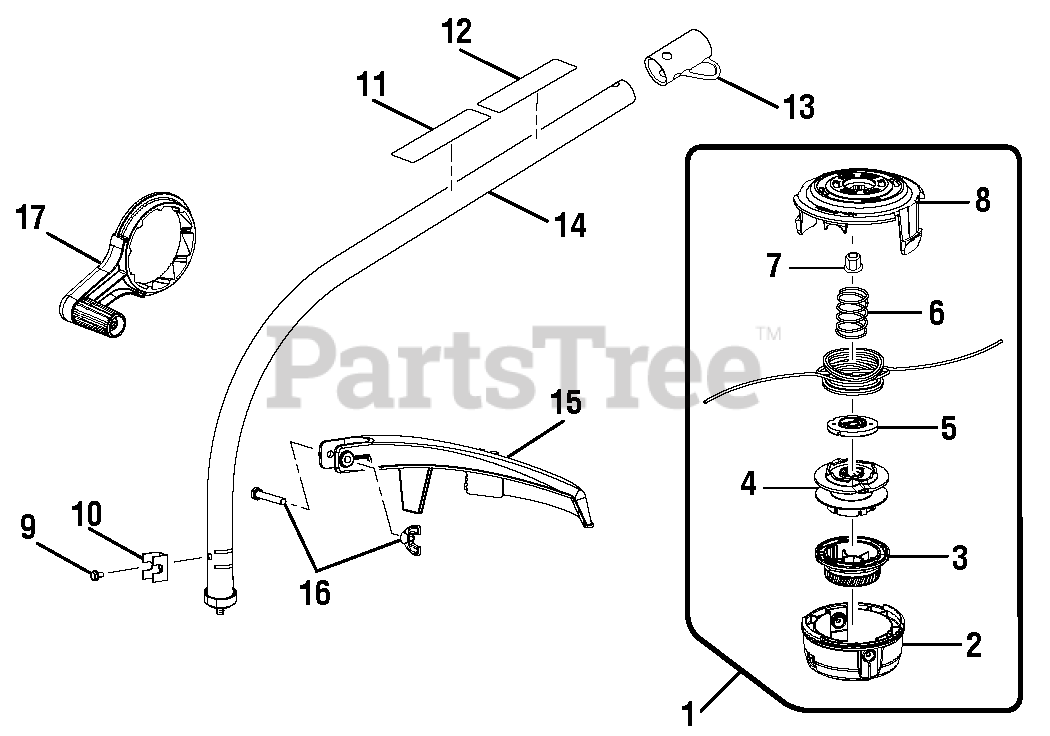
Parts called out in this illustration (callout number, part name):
1	Trimmer Head Assembly (.095)
2	Lower Housing
3	Bump Knob (Green)
5	String Guide
6	Compression Spring
7	Hex Nut (M8)
8	Upper Housing
9	Screw (#10-32 x 3/8 in., Hex Washer Hd. S.T.)
11	Expand-it Label
12	Warning Icon Label
13	Storage Hanger Cap
14	Curved Shaft Assembly
15	Grass Deflector Assembly
16	Fastener Kit
17	Crank Handle Assembly
